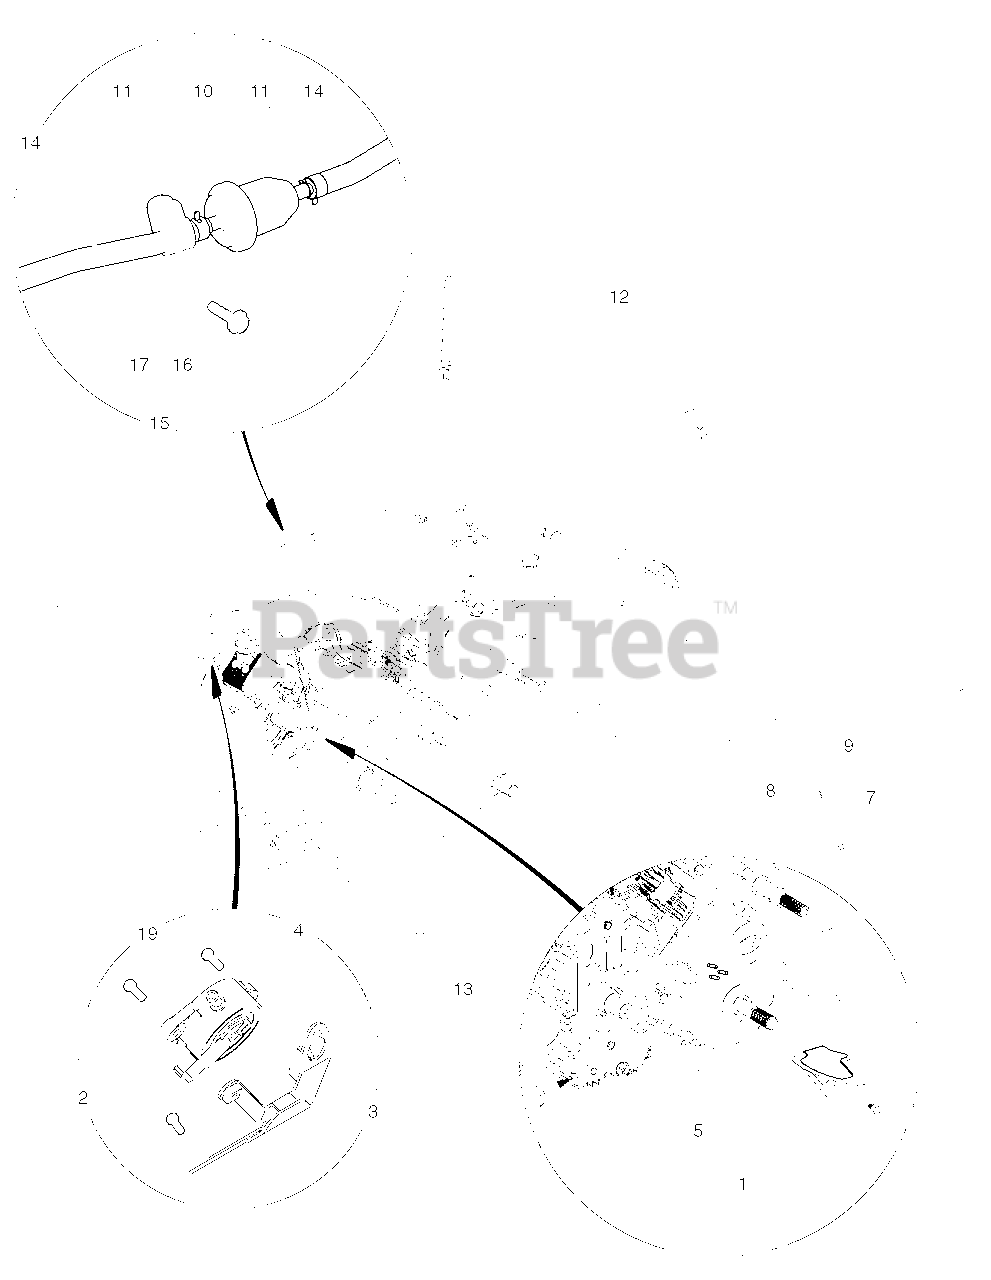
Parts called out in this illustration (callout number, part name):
1	Bolt Flanged Head, M8 X1.25x 16 with Loctite
2	Bolt, Flg, M6 X 1.0 X 16
3	Bracket, Fuel Pump, Fh
4	Pump, Fuel, Impulse, Fh
5	Heat Shield, Header, Gas
6	Instl, Fuel System, Fh680d
7	Clamp, 0.301 ID Hose
8	Hose, Fuel, Vent, 22" Long
10	Filter, Fuel, 30 Micron
11	Clamp, Hose, Ctb 13mm
12	Strap, Tank, Fuel
13	Lock Nut, Flg M8 X 1.25 Nylon
15	Kit, Fuel Line Clamp, 4x4 Khi
16	Screw, M8X1.25X30, Hex
17	P-clamp, Insulated 0.625 In
18	Instr, Kit Fuel Line 4x4 Khi
19	Bolt, Flanged, M6 X 20, Kaw
